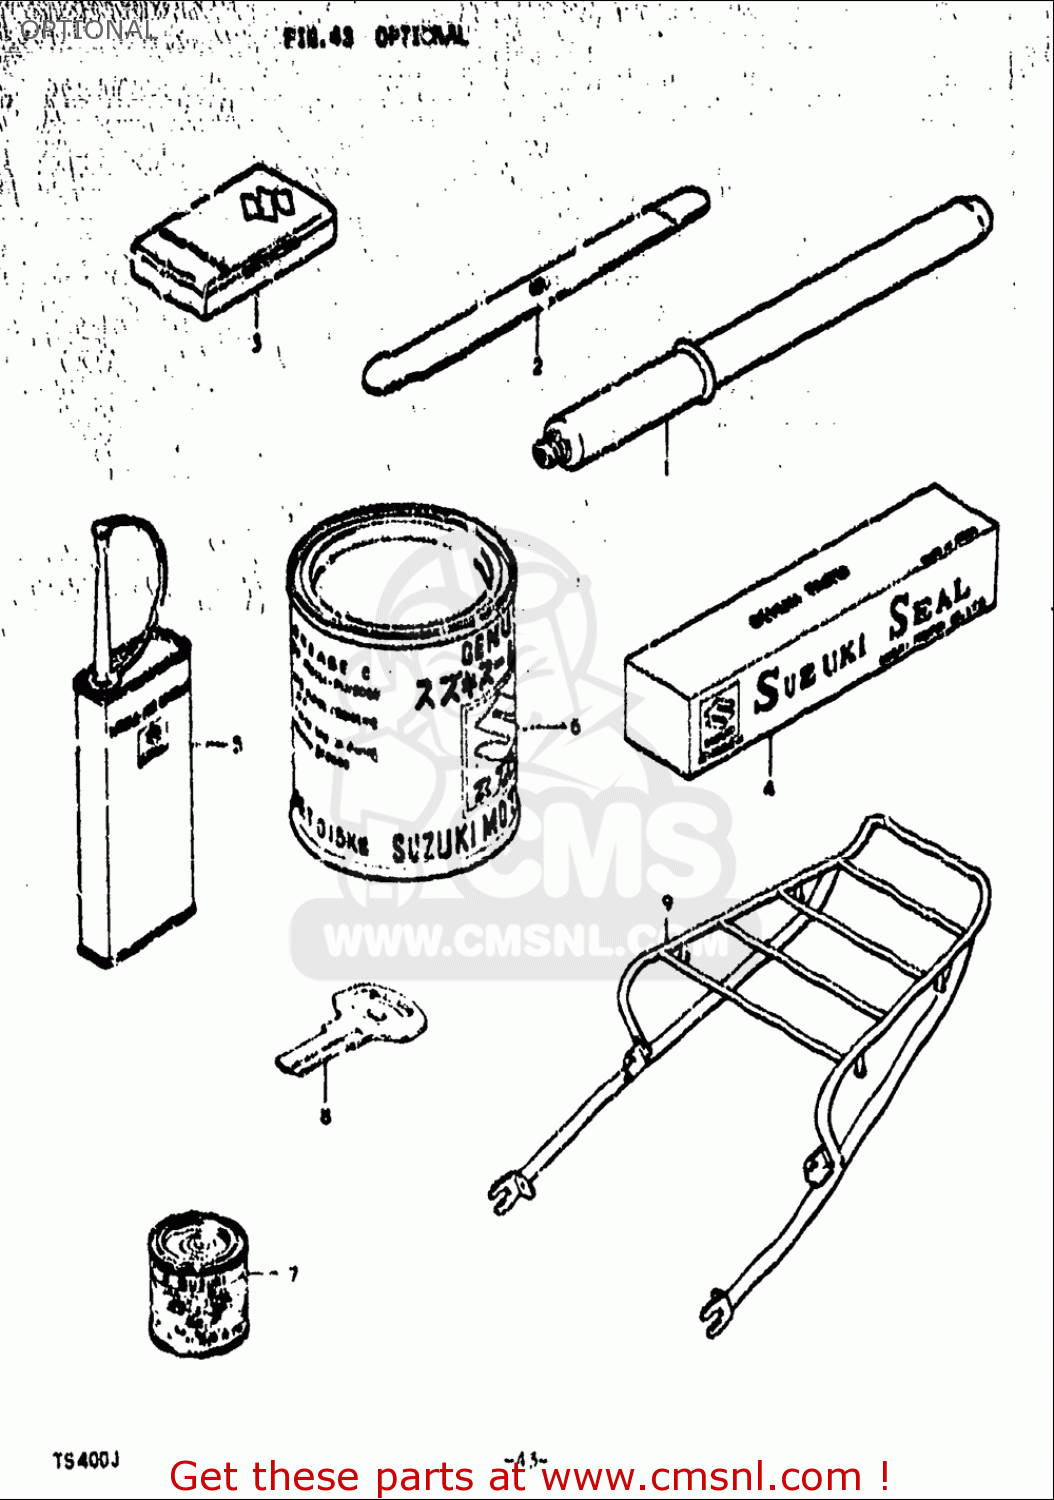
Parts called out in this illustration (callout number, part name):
2	LEVER,TIRE
5	THREAD LOCK NO.1401 CLEAR 200G
6	GREASE(C)EP2 LITHIUM 150G
